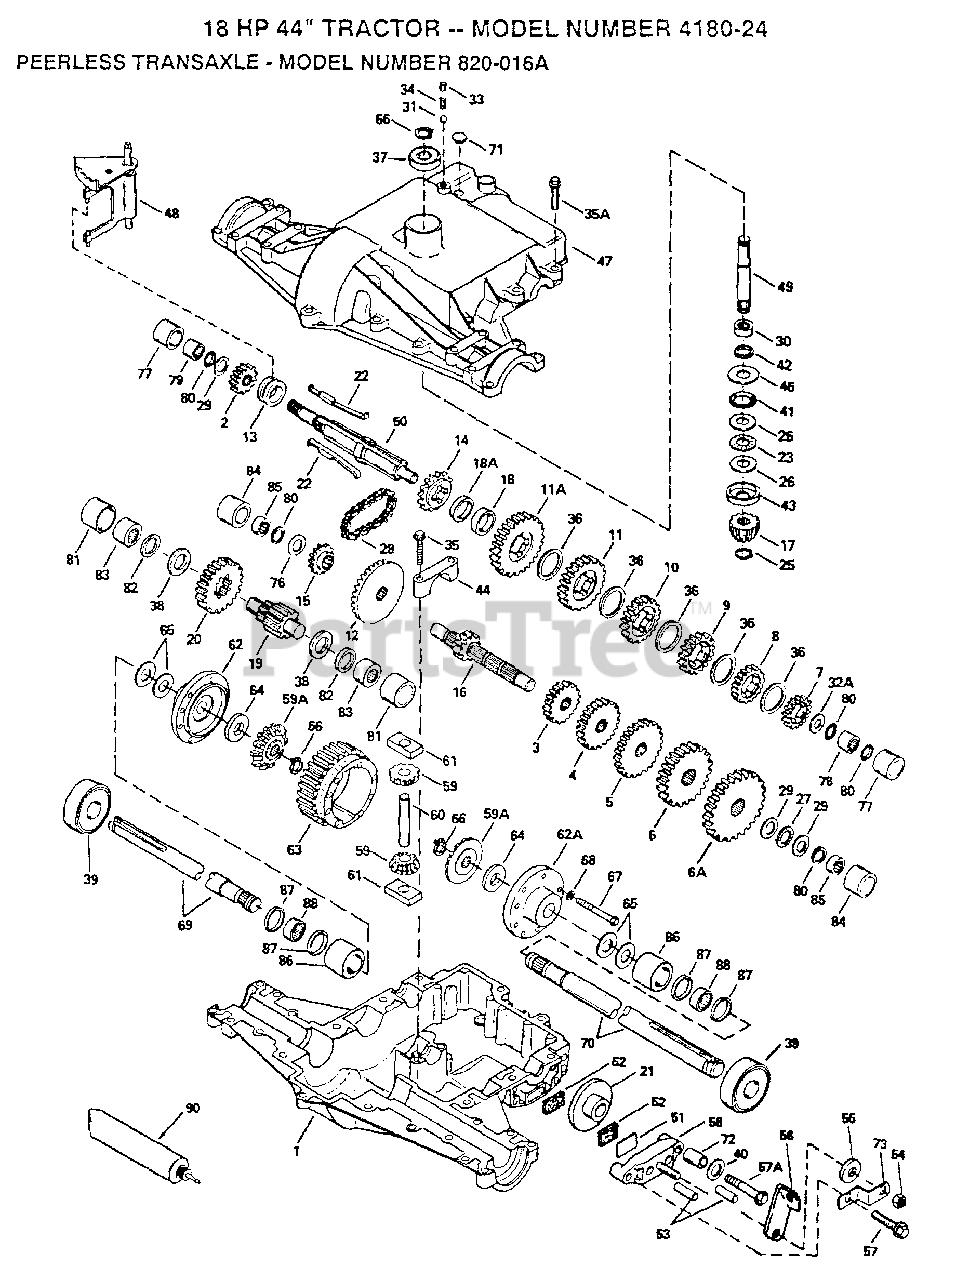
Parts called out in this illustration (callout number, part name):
1	CASE TRANSAXLE
2	GEAR, SPUR, 15T
3	GEAR, SPUR, 12 TEETH
4	GEAR, SPUR, 18 TEETH
5	GEAR, SPUR, 25T
6	GEAR, SPUR, 28T
6A	GEAR, SPUR, 31T
7	GEAR, SPUR, 19T
8	GEAR, SPUR, 22T
9	GEAR, SPUR, 25T
10	GEAR, SPUR, 32 TEETH
11	GEAR, SPUR, 37 TEETH
11A	GEAR, SPUR, 41T
12	GEAR BEVEL, 33T
13	COLLAR SHIFT
14	SPROCKET 18T (REV)
15	SPROCKET 9T
16	SHAFT COUNTER
17	BEVEL PINION, 13T
18	SPACER, .350/.340 THICK
18A	SPACER, .276/.268 THICK
19	SHAFT, OUTPUT, 9T
20	GEAR, OUTPUT, 35T
23	BEARING THRUST
25	RETAINING RING
26	WASHER THRUST
27	THRUST BEARING
28	CHAIN, ROLLER
29	WASHER THRUST
30	BEARING NEEDLE
31	BALL STEEL, 5/16" DIA.
33	SCREW, 3/8-16 X 3/8"
35	SCREW, 1/4-20 X 1-1/4
35A	SCREW HEX HD 5/16-18 X 1-1/4
36	WASHER THRUST
37	BEARING BALL
38	WASHER THRUST
39	BEARING BALL
40	WASHER FLAT
42	OIL SEAL 3/4
43	WASHER CUPPED
44	BEARING CAP
47	COVER TRANSAXLE
48	ROD AND FORK ASSY SHIFT
49	SHAFT INPUT
50	SHAFT BRAKE
51	PLATE BRAKE PAD
54	LOCKNUT 5/16-24
55	WASHER, FLAT
56	LEVER BRAKE
57	SCREW, 1/4-20 X 1-1/4
57A	SCREW FLNG HEX 1/4-20 X 2-1/4
58	HOLDER BRAKE PAD
59	PINION, 10T
61	BLOCK DRIVE
62	CARRIER DIFF THREADED HOLES
62A	CARRIER DIFF
63	GEAR, RING, 31T
65	WASHER THRUST
67	SCREW, 1/4-20 X 2-1/4
68	WASHER LOCK 1/4
69	AXLE, 12-5/16" LONG
70	AXLE, 16-3/16" LONG
71	PLUG, THRDED, 9/16-18
73	BRKT BRAKE LEVER
78	BEARING NEEDLE
79	BEARING NEEDLE
81	SLEEVE STEPPED
82	RING SQ CUT
83	BEARING NEEDLE CAPPED
84	SLEEVE STEPPED
85	BEARING NEEDLE CAPPED
86	SLEEVE STEPPED
87	RING SQ CUT
88	BEARING NEEDLE
90	GREASE BENTONITE, 32 OZ.
